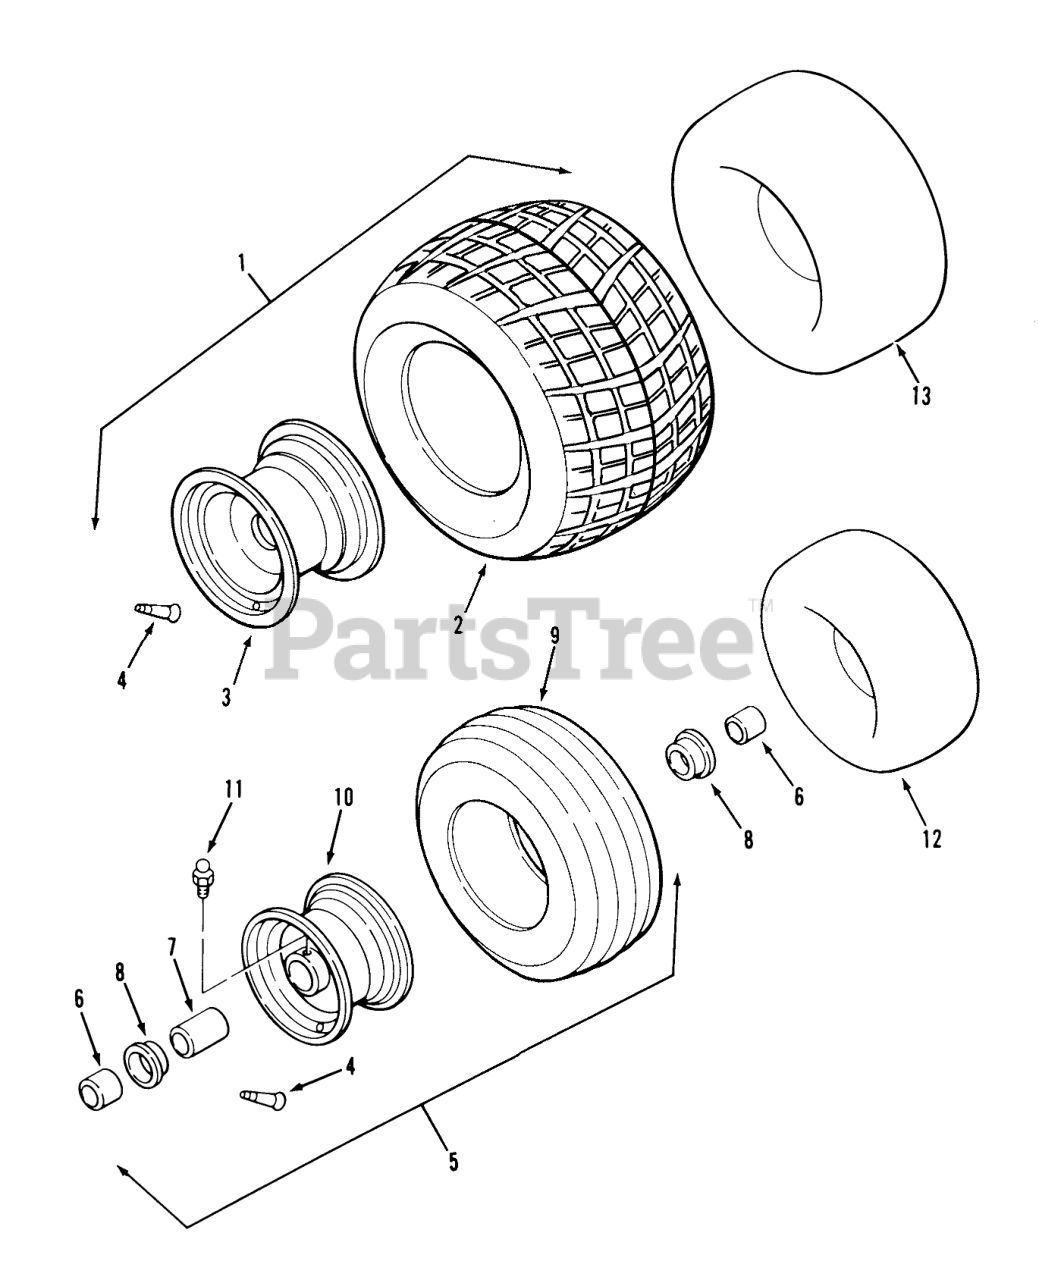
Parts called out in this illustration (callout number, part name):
2	TIRE 22 X 11.00-8
3	Wheel-Rear, Silver
4	VALVE
6	SPACER
7	SPACER FRT WHEEL INN
8	BEARING BALL
9	TIRE-FRT 13X5.00-6
10	WHEEL FT SLUV 10239K
11	Zerk
12	INNER TUBE
13	Tube-Rear
